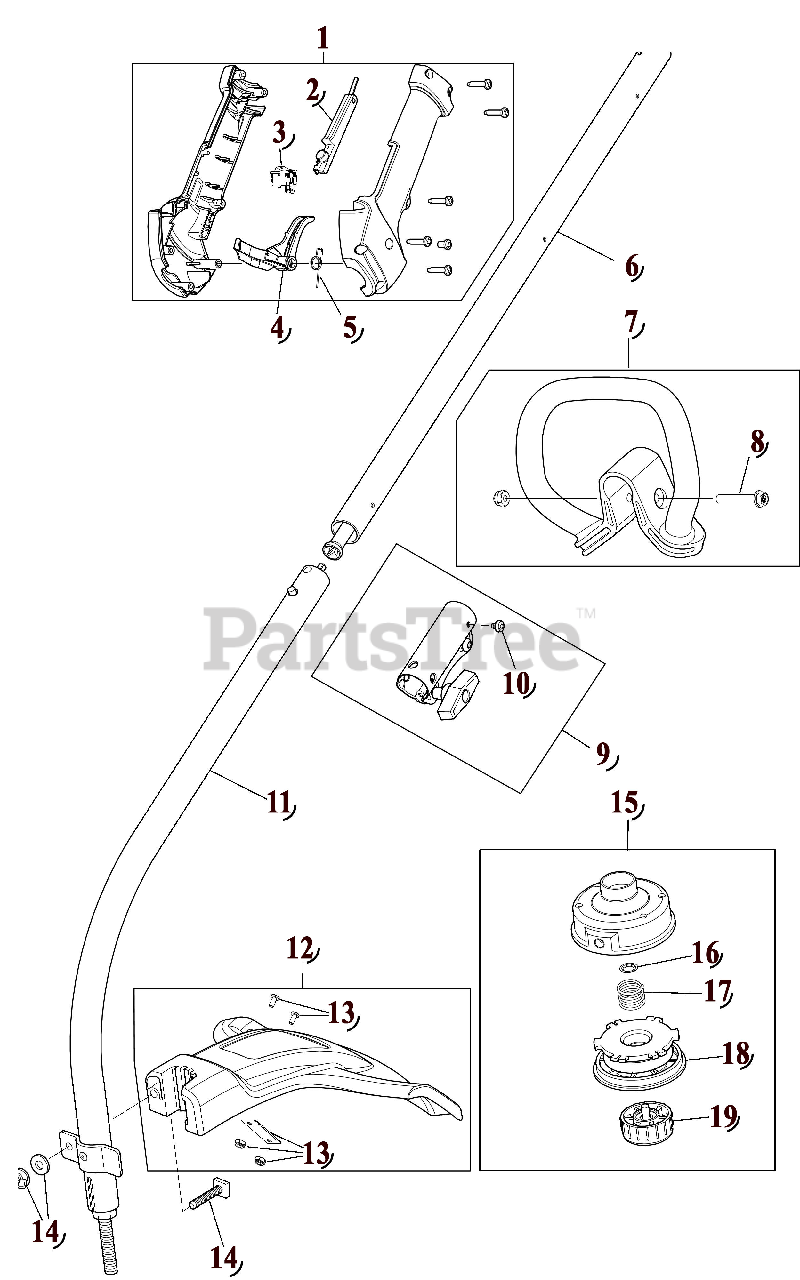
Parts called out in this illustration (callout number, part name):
1	Throttle Housing Assembly (incl. 2 - 5)
2	Throttle Trigger Lock-Out
3	Throttle Switch Assembly
4	Throttle Trigger
5	Throttle Trigger Spring
6	Upper Shaft Housing Assembly
7	D-Handle (incl. 8)
8	D-Handle Bolt
9	Split Boom Coupler (incl. 10)
10	Coupler Anti-Rotation Screw
11	Lower Shaft Housing Assembly
12	Shield Assembly (incl. 13)
13	Blade Assembly
14	Shield Mounting Hardware
15	Outer Spool Assembly (incl. 16)
18	Inner Reel
19	Bump Head Knob Assembly
